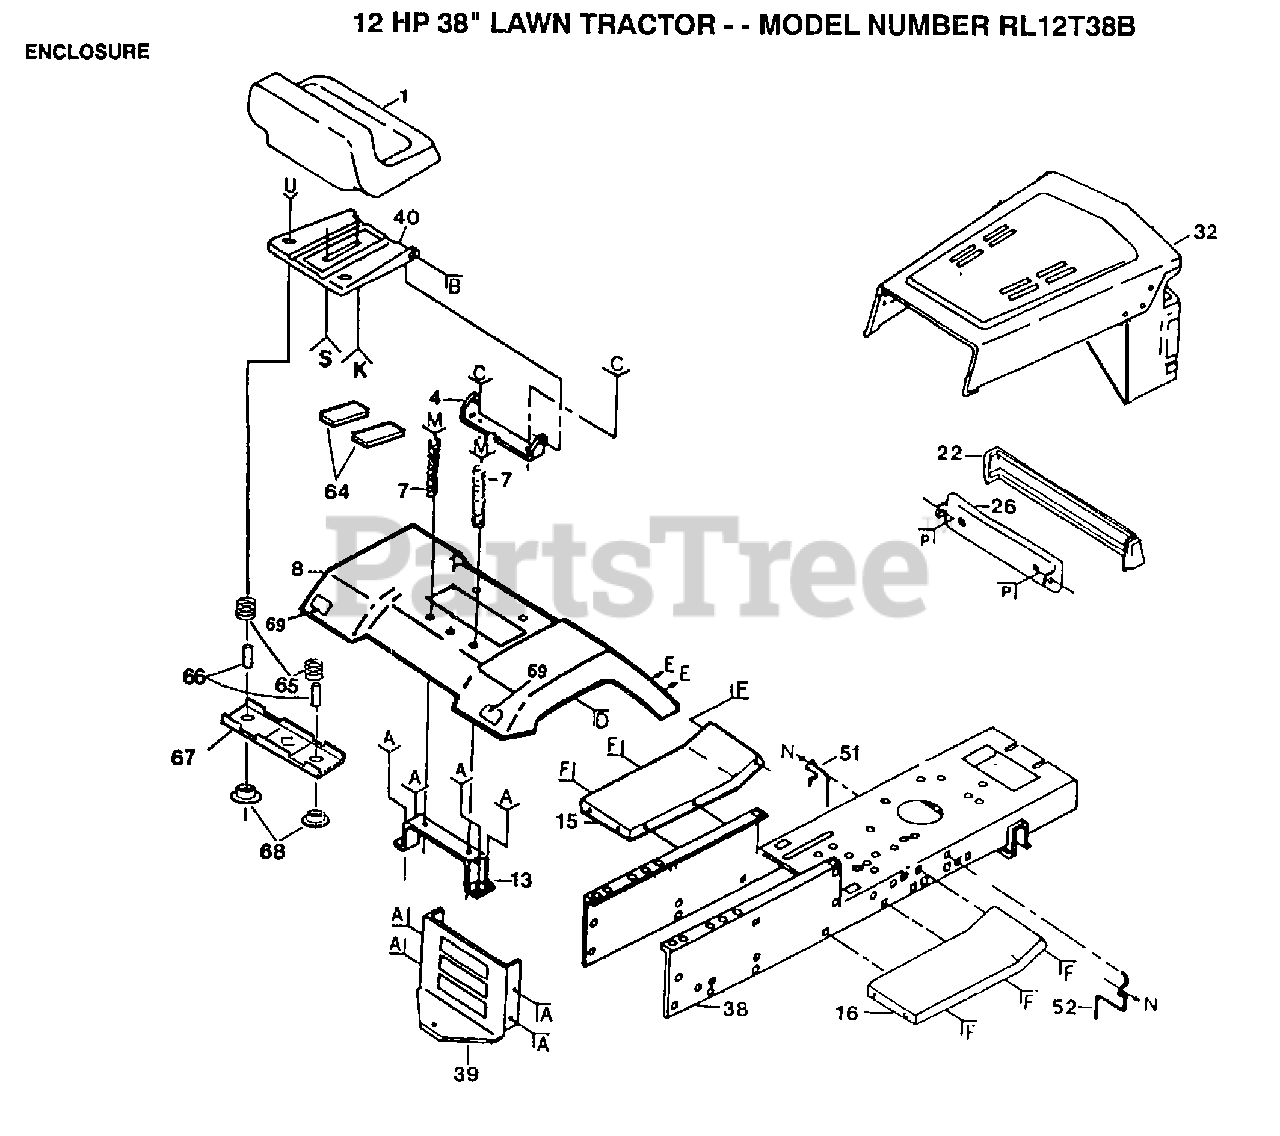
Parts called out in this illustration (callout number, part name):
2	SCREW
3	SCREW GTV
7	SPRING COMPRESSIO
9	WASHER
12	SCREW LT
14	"BOLT,SHOULDER"
15	FOOTREST LH
16	FOOTREST
17	BOLT
21	PAL NUT LT
24	WASHER
27	BOLT
32	HOOD&GRILL ASS'Y
38	CHASSIS ASS'Y
47	WASHER
48	LOCKWASHER
49	WASHER
50	BOLT
51	BELT GUIDE
52	BELT GUIDE
59	WASHER
60	WASHER PM
62	BOLT
64	STRIP FORM
65	SPRING
66	SPACER SPLIT
67	BRKT SWITCH
68	BUSHING
69	REFLECTOR-TAIL YT
